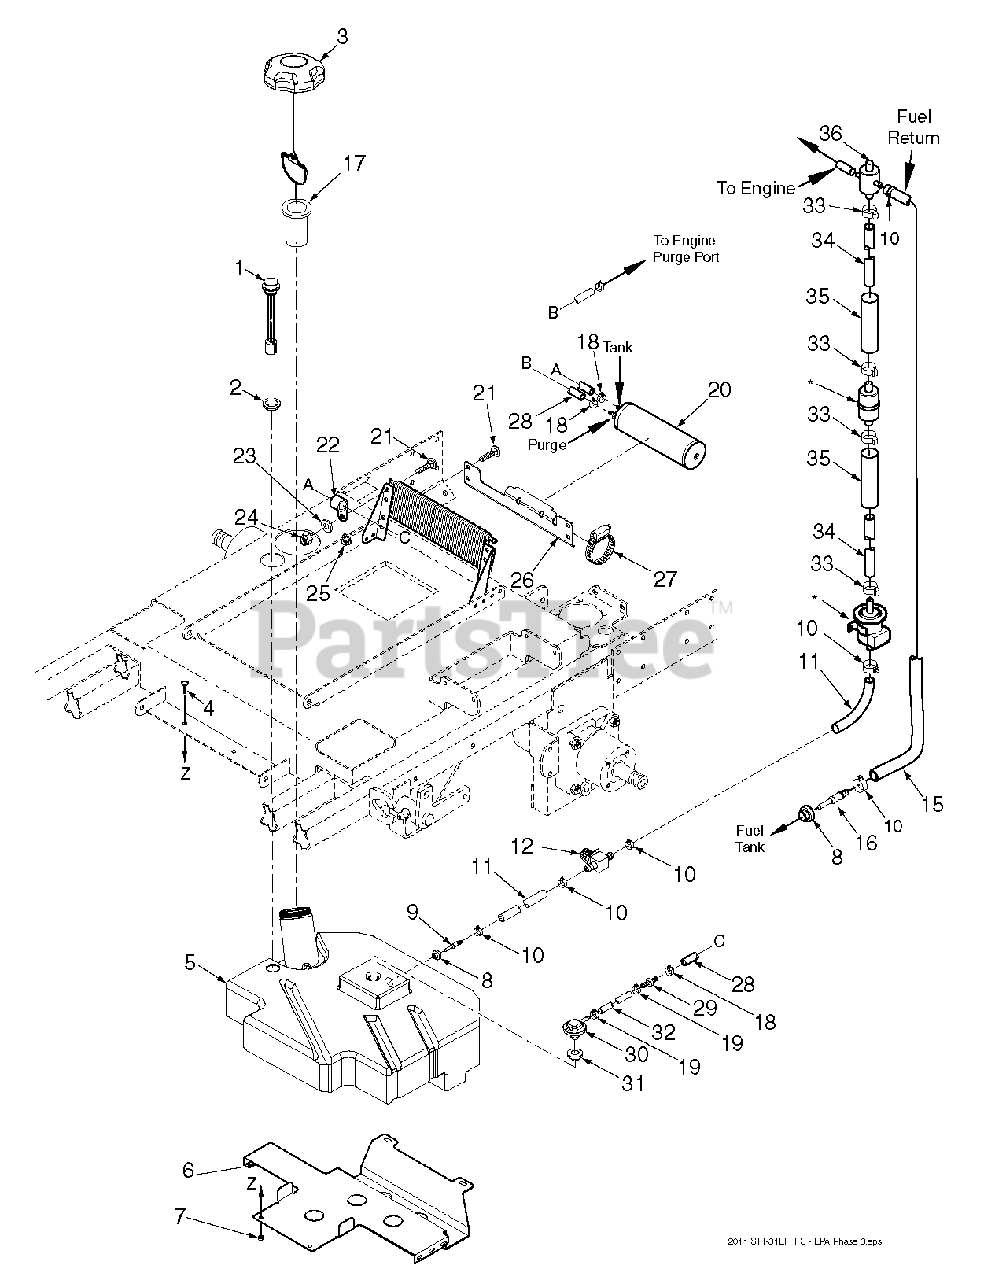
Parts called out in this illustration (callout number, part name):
1	Fuel Gauge Assembly
2	Seal, Fuel Gauge
3	Fuel Cap, Tethered
4	Bolt, Carriage 1/4-20 x 3/4"
5	Fuel Tank Assembly
6	Support Bracket, Fuel Tank
7	Nut, 1/4-20 Serrated Flange
8	Bushing, .56 Dia. Viton
9	Hose Fitting
10	Clamp, Fuel Hose 5/16" I.D.
11	Fuel Hose, 5/16" I.D. Non-Perm
12	Valve, Fuel Shut-Off
13	Clamp, .87" Max. Dia
14	Fuel Hose, 1/2" I.D. Non-Perm
15	Fuel Hose, 1/4" I.D. Non-Perm
16	Return Fitting, Straight
17	Tube, Fuel Tank Insert - 6"
18	Clamp, Vapor Recovery Hose 3/16"
19	Clamp, Fuel Hose 7/32 ID
20	Carbon Canister
21	Bolt, Carriage 1/4-20 x 3/4"
23	Flatwasher, 1/4-.281 x .562 x .049
24	Nut, 1/4-20 Elastic Stop
25	Nut, 1/4-20 Serrated Flange
26	Bracket, RH Canister Mounting
28	Hose, 3/16
29	Mender, 1/4 x 3/16 w/.02 Hole
30	Valve, Rollover
31	Grommet, Viton
32	Hose, 1/4" Vapor Recovery
33	Fuel Clamp, 5/16" Oetiker
34	Fuel Hose, 5/16" Non-Perm
35	Shield, Flexible
36	Regulator Assembly, Fuel Pressure
